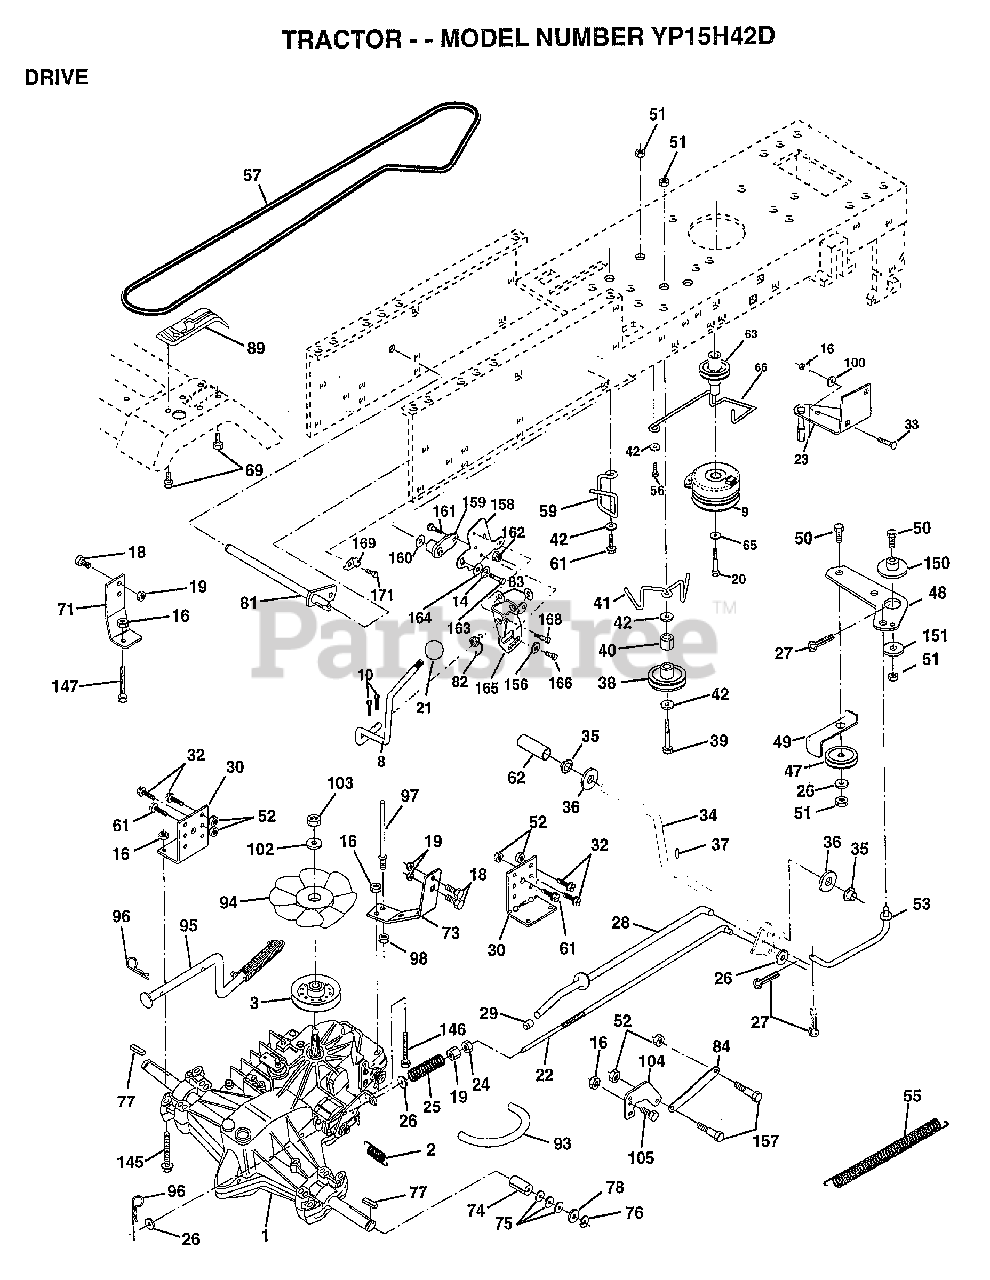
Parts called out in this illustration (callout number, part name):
2	SPRING RET BRAKE
3	PULLEY.TRANSAXLE
8	ROD.SHIFT.FENDER.ADJ.LT.CRD
9	CLUTCH.ELECT.EVX.
10	PIN COTTER 1/8
14	LOCKWASHER
16	NUT
18	BOLT
19	NUT
20	BOLT.7/16-20X4.25
21	KNOB DLX BLK/BLK
22	ROD.BRAKE.HYDRO.
23	BRACKET.CLUT.MTG.
24	NUT
25	SPRING ROD LT
26	WASHER
27	COTTER PIN
28	ROD.BRAKE.PARK.LT
29	PLUNGER CAP T
30	TRANSAXLE MTG BKT
32	BOLT
33	BOLT
34	SHAFT ASM-PEDAL F
35	NYLON BEARING
36	WASHER LT
38	FLAT IDLER PULLEY
39	BOLT
40	SPACER T
41	"KEEPER,BELT.IDLER FLAT"
42	WASHER
48	BELLCRANK.CLUTCH
49	RETAIN BELT
53	"LINK, CLUTCH T"
55	"SPRING, RETURN LT"
57	"BELT.GD DRV 82"""
59	KEEPER BELT CNTSP
61	SCREW
62	"COVER,PEDAL"
63	PULLEY.CLUTCH.EVX
65	LOCKWASHER
66	KEEPER-BELT
69	SCREW HEXWSH H-L
71	STRAP TORQ LH HYD
73	"STRAP-TORQUE,RH"
74	SPACER SPLIT
75	WASHER
76	E-RING LT
77	SQUARE KEY
78	WASHER
81	SHAFT.ASM.CROSS
82	"SPRING,TORSION"
83	WASHER
84	LINK.TRANSAXLE.LT/YT
89	CONSOLE.SHIFT.LT
93	"LINE FUEL HYD 4"""
94	"FAN 7"" HYDRO"
96	RETAINER M
97	BOLT KEEPER RH
98	NUT
100	WASHER M
102	WASHER BELLEVILLE
104	ARM CONTROL HYDRO
105	SCREW CAP 5/16-18
145	BOLT.HEX.FLGHD
146	BOLT.HEX.FLGHD.
147	BOLT.HEX.FLGHD
150	BUSHING.BELLCRANK.GRD.DR
151	WASHER
156	WASHER.SRRTD.5/16
157	"BOLT,SHOULDER"
158	BRKT.SHIFT.MOUNT
159	HUB.SHIFT
160	WASHER
161	BOLT T
164	WASHER.5/8X.281X10GA
165	BRKT.PIVOT.LEVER
166	SCREW.5/16-18X5/8
168	BOLT.SHOULDER.5/16-18X.561
169	PLATE.FASTENING
171	SCREW LT
